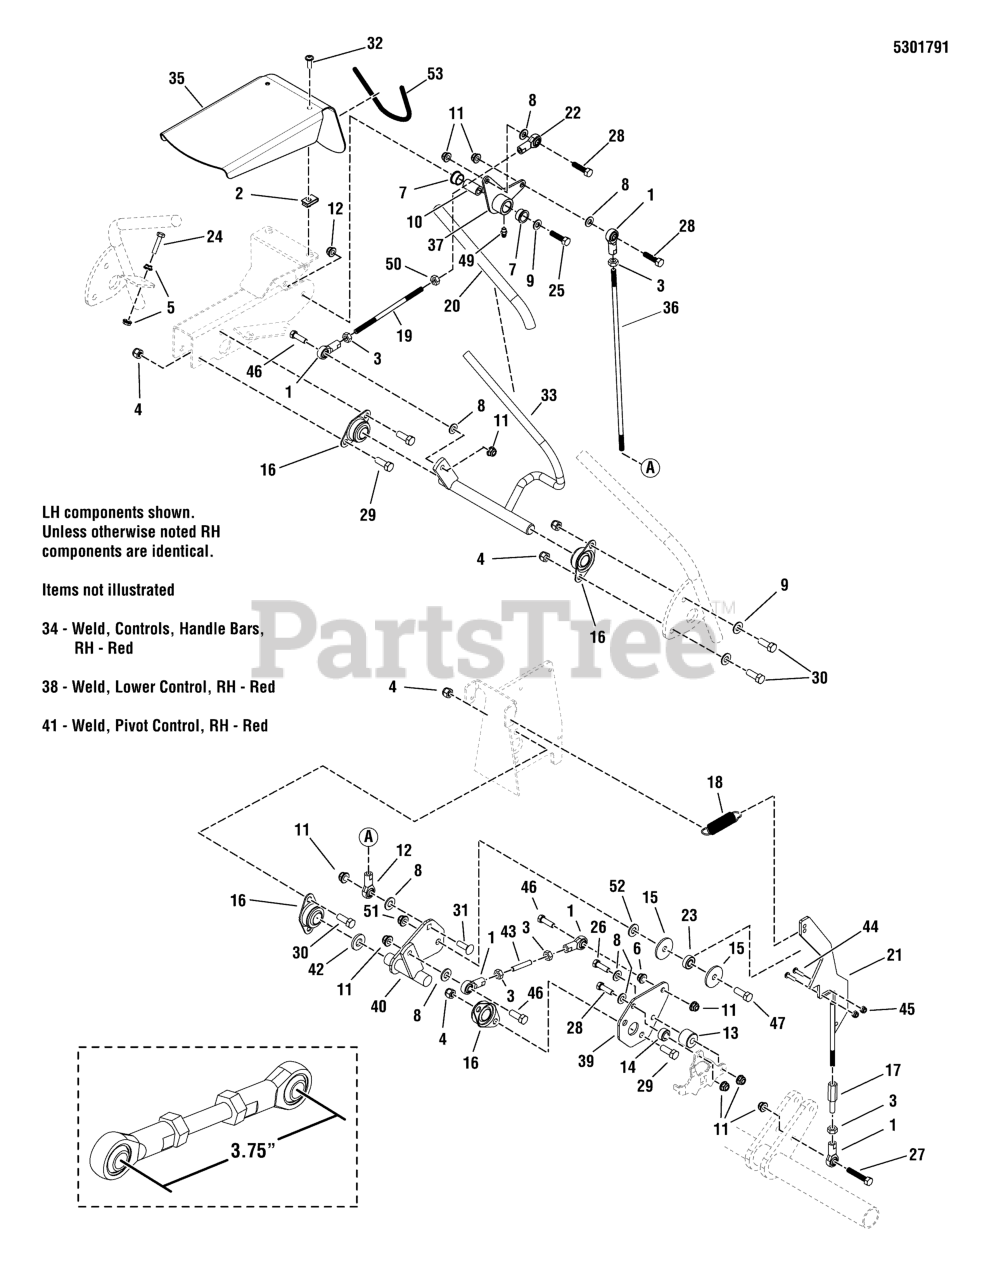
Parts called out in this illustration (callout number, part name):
1	BALL JOINT 5/16-24 RH FEMALE STAMPED STL
2	BODY CLIP, 1/4-20 X 1/2 DEEP
3	NUT, 5/16-24 HEX
4	NUT, 3/8-16 HEX NYLON LOCK
5	NUT, 1/4-20 HEX SERR. FLANGE
6	NUT, 5/16-18 HEX SERRATED FLANGE (SMALL)
7	BUSHING-0.628IDX0.751ODX0.400LG PWDR MTL
8	WASHER, 5/16" SAE
9	WASHER, 3/8 SAE
10	SPACER-0.39 IDX0.625ODX1.15 LG CASE HARD
11	NUT, 5/16-18 HEX NYLOCK FLANGE
12	NUT, 3/8-16 HEX NYLOCK FLANGE
13	SPACER, .39 X 1.00 X .75
14	SPACER, .39 X .75 X .38
15	WASHER, .390 X 1.50 X .109, YZ
16	BEARING, BRONZE FLANGE, 3/4"
17	ADJUSTER, ROD LINKAGE 5/16-24
18	SPRING-EXT, 3.281 x .751 x .075 WIRE
19	ROD, HYDRO LINKAGE, 7.50
20	GRIP, FOAM, .48 x 10 x .125 Black
21	WELD, CONTROL RAMP, EVO
22	BALL JOINT 5/16-24 LH FEMALE STAMPED STL
23	BEARING, .375" ID X .875" OD X .341" THK
24	BOLT, 1/4-20 X 1-1/4, GD5
25	BOLT, 3/8-16 X 2, GD5, CZ
26	BOLT, 5/16-18 X 1-1/2 GD5 YZ
27	BOLT, 5/16-18 X 1 GD5 YZ
28	BOLT, 5/16-18 X 1-1/8 GD5
29	BOLT, 3/8-16 X 3/4" GD5 CZ
30	BOLT, 3/8-16 X 1" GD5 CZ
31	BOLT, 5/16-18 X 1, CARRIAGE
33	WELD,CONTROLS, HANDLE BARS, LH, EVO -RED
35	GUARD, MOTION CONTROLS, SNP PRO 52, RED
36	ROD, HYDRO LINKAGE, 14.63
37	WELD, PIVOT, CONTROL, LH - RED
39	PLATE, PUMP CONTROL, 48/52 - RED
40	WELD, LOWER CONTROL, LH - RED
42	SPACER, .76 X 1.00 X .25
43	LINK, STUD
44	SCREW, #10-24 X 3/4 ROUND PHILLIPS
45	NUT, #10-24 HEX NYLON LOCK
46	BOLT, 5/16-18 X 1-1/4 GD5 YZ
47	BOLT, 3/8-16 X 1-1/4" GD5 CZ
48	BOLT, 5/16-18 X 3/4 GD5
49	GREASE FITTING, 1/4-28 STRAIGHT
50	NUT, 5/16-24 HEX, LH
51	NUT, 3/8-16 HEX SIDE LOCK
52	WASHER, 3/8 GD.9 FLAT
53	BLACK BODY MOLDING, 16" LONG
